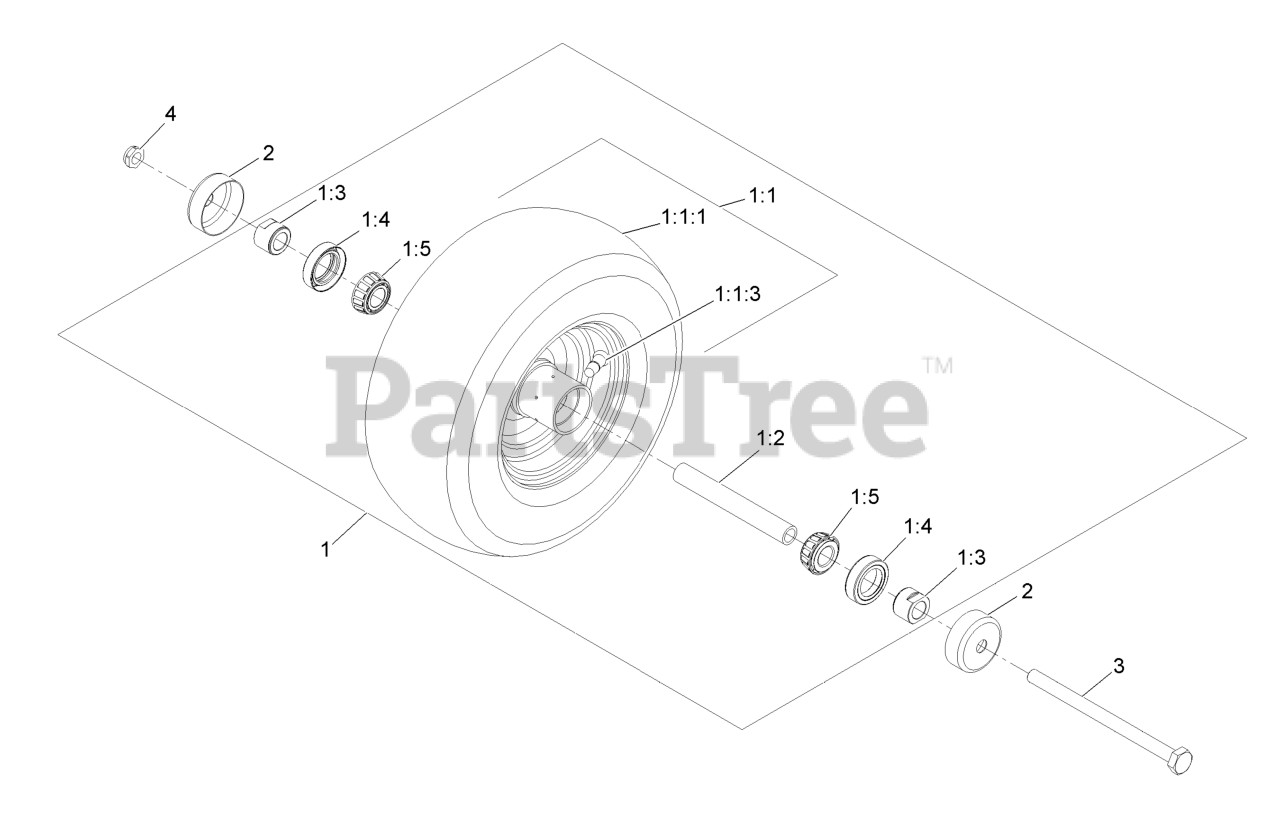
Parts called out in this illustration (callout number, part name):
1:1:3	VALVE
1:3	SPACER-NUT
1:4	SEAL-CASTER
1:5	BEARING-CONE, TAPERED ROLLER
2	GUARD-SEAL
3	SCREW-HH
4	NUT-HEX
